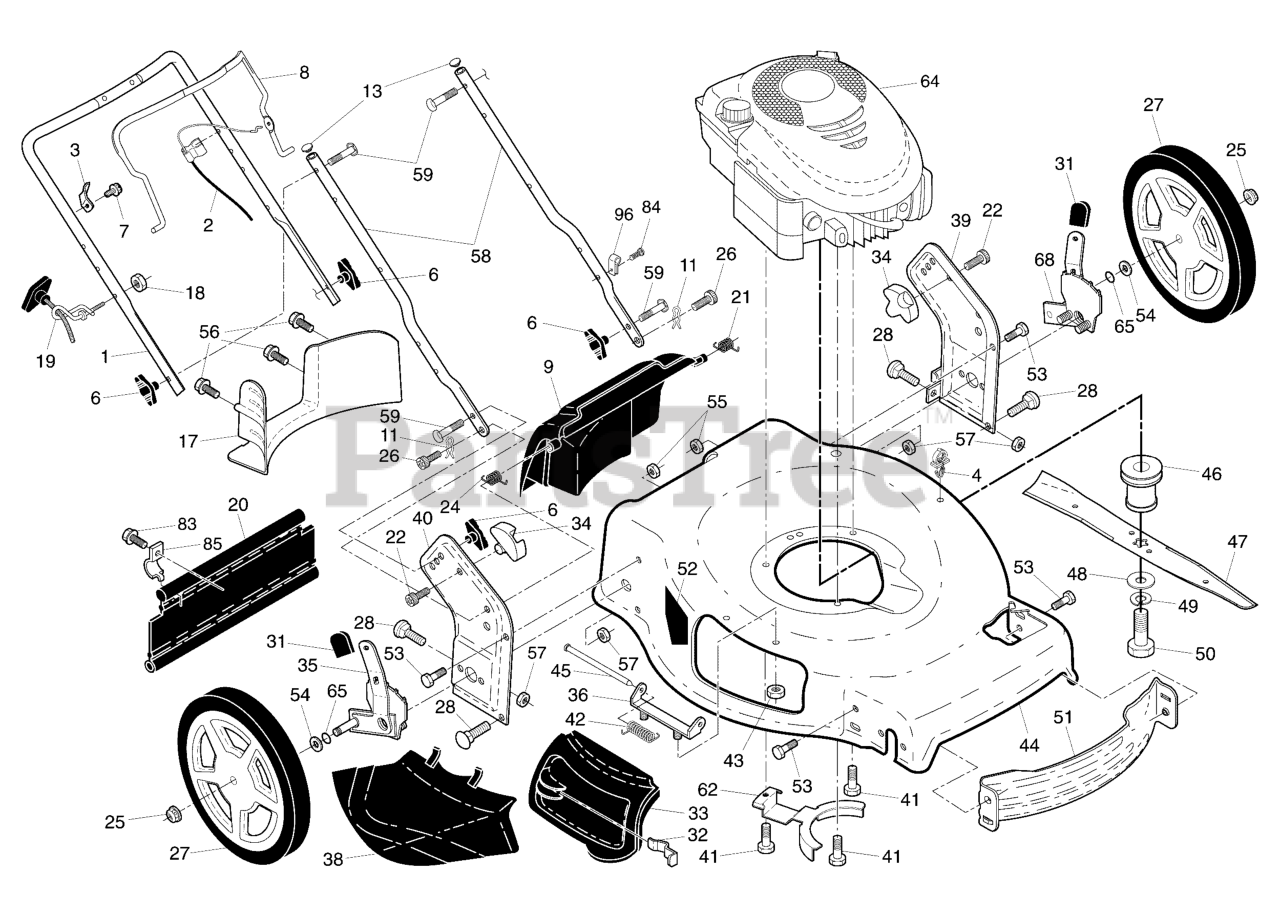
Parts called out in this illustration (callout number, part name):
1	Upper Handle
2	Cable, Engine Zone Control
3	Up-Stop Bracket
4	CLIP, Push-In Hinged
6	Knob, Handle
7	SCREW, Hex Head, Threaded, Rolled, #10-16 x 5/8
8	Control Bar
9	Rear Door Assembly
11	Hairpin, Door/Handle Pivot
13	Plug, Lower Handle Bar
17	Rear Baffle
18	Nut, Hex, with Lockwasher Insert, 1/4-20
19	GUIDE, Rope
20	Rear Skirt
21	Spring, Rear Door, LH, Black
22	Screw, Panhead, Torx #20
24	Spring, Rear Door, RH, Grey
25	Nut, Hex, Flangelock 3/8-16
26	Screw, Door/Handle Pivot
27	Wheel & Tire Assembly, Rear
28	Bolt Rdhd Sqnk 5/16-18 x 5/8
31	Selector Knob
32	Latch, Mulcher Door
33	Mulcher Door
34	Pivot Bracket
35	Kit, Wheel Adjuster, Rear, RH
36	Hinge Bracket Assembly
38	Discharge Deflector
39	Handle Bracket, LH
40	Handle Bracket, RH
41	Screw, Hex Head, Threaded, Rolled, 3/8-16 x 1-1/5
42	Spring, Torsion
43	Nut, Hex, Flanged 1/4-20
44	Kit, Lawn Mower Housing
45	Rod, Hinge
46	Blade Adapter / Pulley
47	Blade, 22"
48	WASHER, Hardened
49	Washer, Lock Hvy Hlcl Spr 3/8
50	Screw, Machine, Hex Head, 3/8-24 x 1-3/8, Grade 8
51	Front Baffle
52	Decal Deflect WRN. Cutfinger
53	Screw, Hex Head 5/16-18
54	WASHER, Flat, 3/8
55	Nut, Hex, Flanged 1/4-20
56	Screw, Hex Washer Head, #13 x 3/4
57	Nut, Hex 3/8-16
58	Bar, Handle, Lower
59	Bolt, Carriage 1/4-20 x 1-1/2
62	Belt Retainer
64	* Engine, Briggs & Stratton
64	ENGINE, Briggs & Stratton
65	O-Ring
68	Kit, Wheel Adjuster, Rear,LH
83	SCREW, Tapping, Hex Washer Head #10-24
84	Fastener, Push
85	Mounting Bracket, Skirt
96	Clip, Cable
